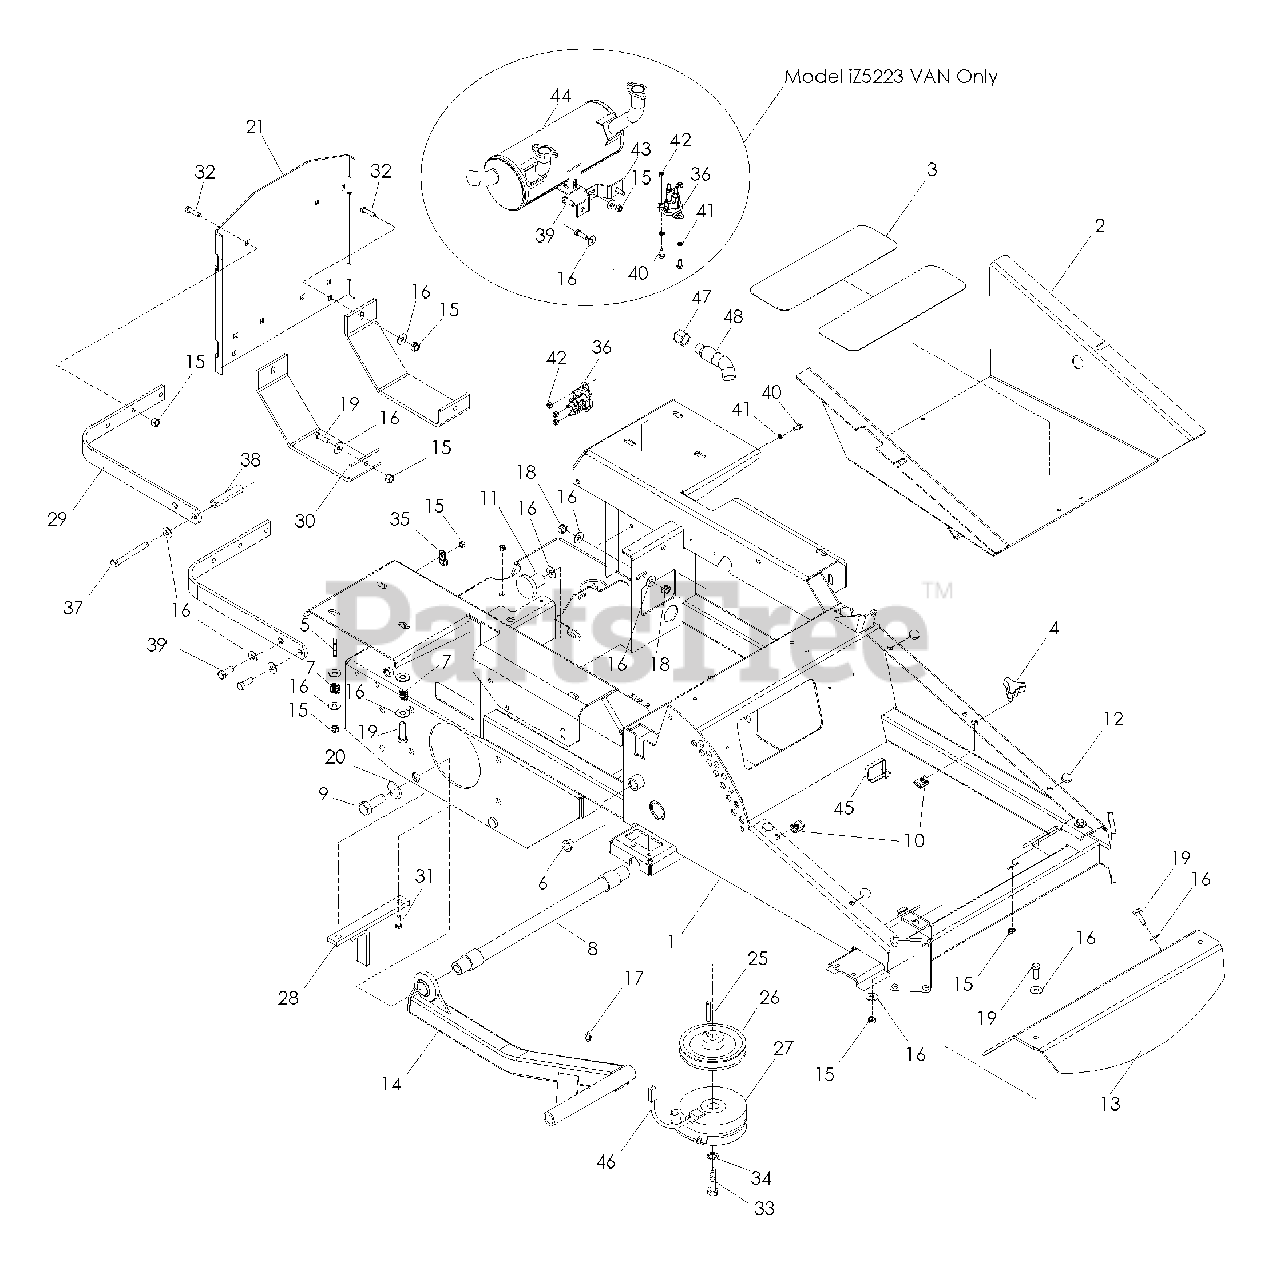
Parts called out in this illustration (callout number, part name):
1	FRAME w/DECALS
2	FOOT PLATE w/DECALS
3	PAD, ABRASIVE
4	KNOB w/STUD
5	TANK-STUD FUEL
7	SPRING, FUEL TANK
8	STRUT MOUNT
9	HCS 5/8-11 x 2
10	NUT 5/16-18, U-TYPE
12	GROMMET, BUMPER
15	NUT 5/16-18 HEX NYLOC
16	WASHER 5/16 STD FLT
17	ZERK, STRAIGHT 1/4-28
18	NUT 5/16-18 HEX CTRLK
19	HCS 5/16-18 x 1
20	WASHER 5/8 SPLIT LOCK
21	REAR GUARD
21	REAR GUARD MODEL iZ25
22	HCS 3/8-16 x 3/4
23	WASHER 3/8 FLAT STD
24	NUT 3/8-16 HEX NYLOC
25	KEY, 1/4 SQ x 1 1/4
27	PULLEY MODELS iZ25, iZ6125, iZ5225XP-BF
28	CLUTCH MODELS iZ25, iZ6125, iZ5225XP-BF
28	CLUTCH MODELS iZ4217, iZ4819, iZ4217C
28	CLUTCH MODELS iZ4821BF, iZ4821 iZ5223 VAN, iZ5223
29	CLUTCH TIE DOWN
31	SKID PLATE
32	HCS 5/16-18 x 1 3/4
33	RHSNB 5/16-18 x 1
34	HCS 7/16-20 x 2 1/2
35	HCS 7/16-20 x 2 3/4 iZ5223 VAN
36	LOCKWASHER 7/16
37	CLAMP, DOUBLE TUBE
38	SOLENOID MODELS iZ4217, iZ4819, iZ4217C, iZ4821BF, iZ4821, iZ5223 VAN
39	HCS 5/16-18 x 4 MODELS iZ4217, iZ4819, iZ4217C, iZ4821BF, iZ4821 iZ5223 VAN
40	SPACER MODELS iZ4217, iZ4819, iZ4217C, iZ4821BF, iZ4821, iZ5223 VAN
41	HCS 5/16-18 x 1
42	HCS 1/4-20 x 5/8
43	WASHER 1/4
44	NUT 1/4-20 HEX NYLOC
45	BRACKET, MUFFLER
47	TIE, PLASTIC
48	CLUTCH HARNESS MODELS iZ4217, iZ4819
49	PLUG, OIL DRAIN MODELS iZ25, iZ5223VAN, iZ5225XPBF, iZ5223, iZ6125
50	HOSE, OIL DRAIN MODELS iZ25, iZ5223VAN, iZ5225XPBF, iZ5223, iZ6125
